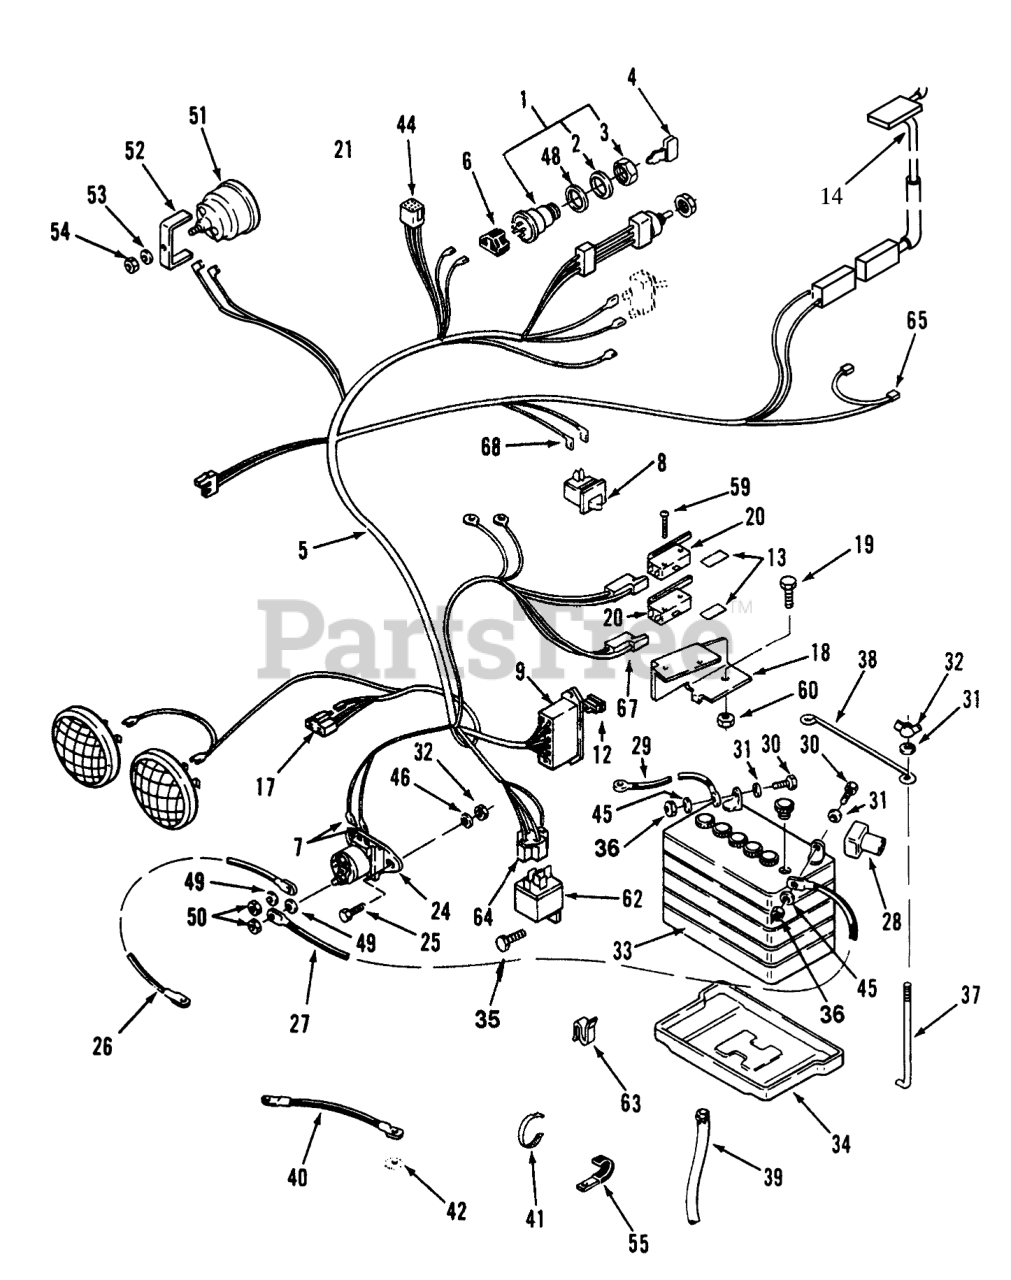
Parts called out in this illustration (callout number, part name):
1	Switch-Ignition (Incl. Ref. #2 & 3)
2	WASHER-LOCK
4	KEY-IGNITION
5	WIRING-HARNESS & DIA
6	CONNECTOR BODY ELECT
7	TERMINAL 10
8	SWITCH INTERLOCK
9	FUSE-HOLDER 4 WAY
12	FUSE-BLADE, 15 AMP
13	BARRIER - SWITCH
14	SWITCH-SEAT
17	5-CONTACT CONN BODY
18	BRACKET-SWITCH
19	Bolt
20	SWITCH
24	SOLENOID
25	Screw
26	ASSY WIRE
27	CABLE-BLACK
28	Boot
29	ASSY WIRE
30	SCREW-HH
31	WASHER-FLAT
32	NUT-WING
33	Battery
34	TRAY-BATTERY
36	NUT-LOCK, INSERT
37	HOOK-BATTERY RETAIN
38	HOLDDOWN-BATTERY
39	TUBE-21" BATTERY DRAIN
40	WIRE GROUND
41	PLASTIC TIE
42	WASHER-LOCK, INTERNAL
44	Terminal
45	WASHER-LOCK
48	Washer
49	WASHER-LOCK
50	NUT-JAM
51	Meter-Hour (Incl. Ref. #52-54)
52	CLAMP-HOUR METER
53	LOCKWASHER
54	Nut
55	CLIP
59	Screw
60	NUT HEX 4-40 ELAST
62	RELAY
63	CLIP-CABLE
64	TERMINAL 10
65	Sur-Plug
68	Terminal
